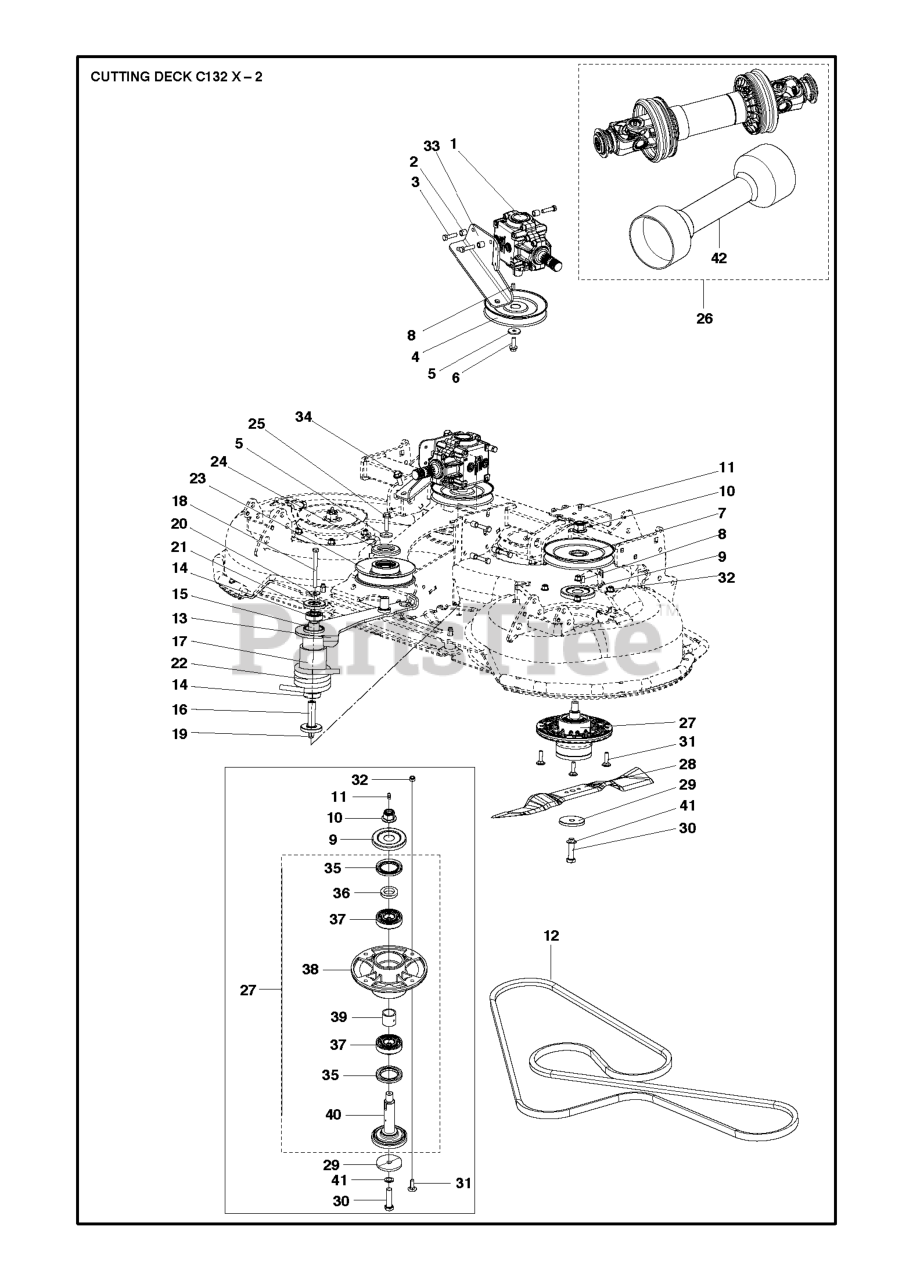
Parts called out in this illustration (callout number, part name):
11	GREASE NIPPLE
14	BALL BEARING
17	SPACER, IDLER PIVOT
19	BLIND RIVET NUT
21	DUST SHIELD
25	SCREW EHHFM
28	BLADE REAR DISCHARGE/MULCH C13
32	NUT FLANGE
37	BALL BEARING 6305 C3
41	SPRINGWASHER
